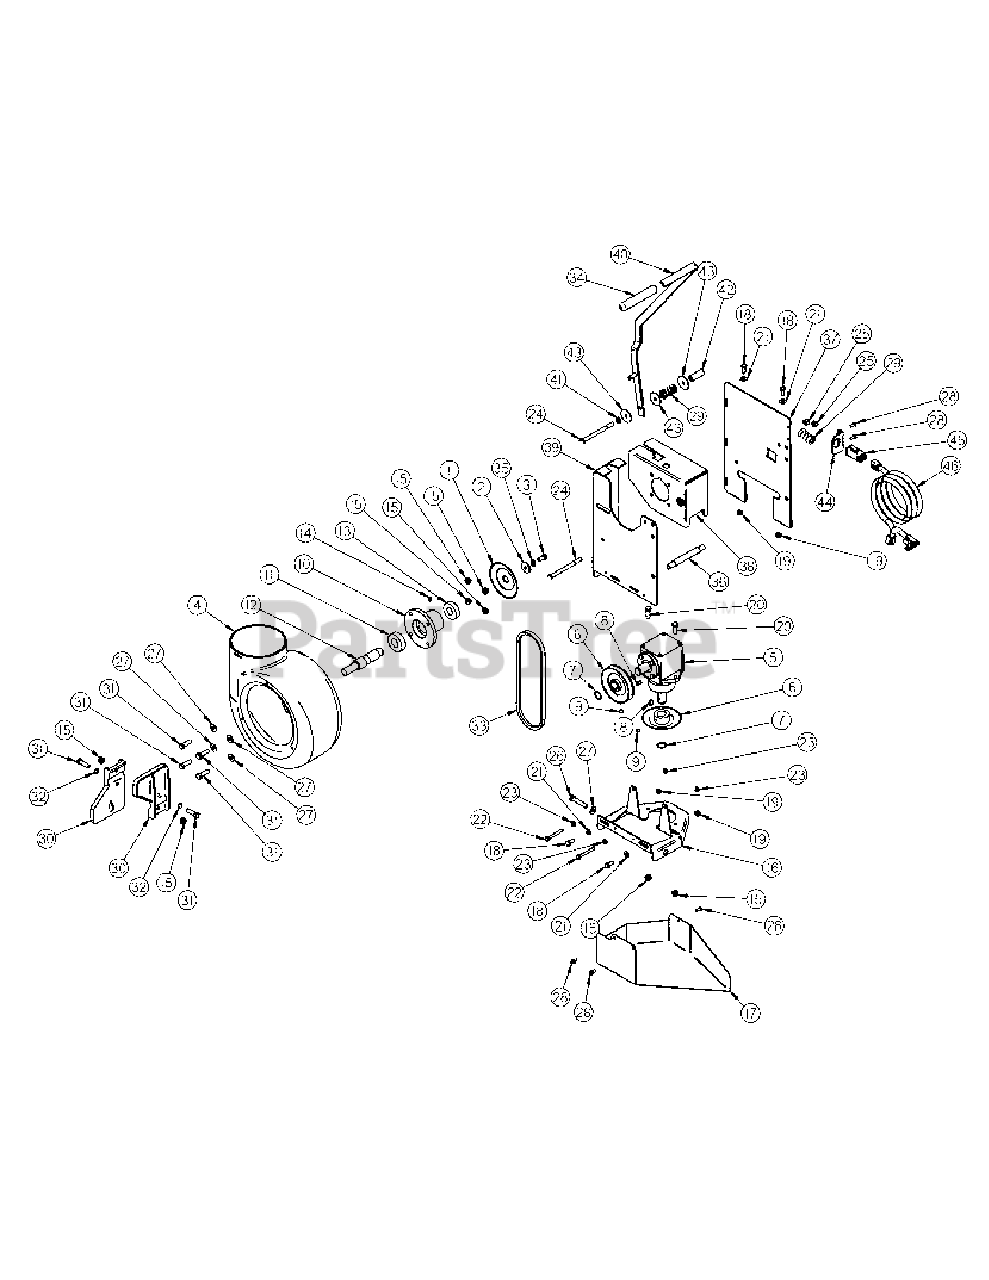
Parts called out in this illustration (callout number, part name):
1	'A' PULLEY FOR DECK DRIVE PTO
2	1.187 OD x .380 ID x .187 WASHER
3	3/8"-16 x 3/4" HHCS
4	BLOWER HSG.
5	GEAR BOX
6	PULLEY ASSY. FOR GEAR BOX
7	7/8" SNAP RING
8	#9 WOODRUFF KEY
9	5/16-18 SET SCREW
10	PTO SHAFT HOUSING
11	BEARING 2.0472 OD, 0.9843 ID, 0.5906 W (6205RS PEER)
12	PTO SHAFT
14	1/4"-28 ZIRC FITTING
15	3/8"-16 FLANGE NUT
17	GEAR BOX PULLEY GUARD
18	5/16"-18 x 3/4" HHCS
19	5/16"-18 FLANGE NUT
20	3/8"-16 x 1" HHCS
21	1/4" FLAT WASHER .75 OD x .314 ID x .060 T
22	1/4"-20 x 2-1/4" HHCS
23	1/4"-20 FLANGE NUT
24	3/8"-16 x 4-1/2" HHCS G5
25	3/8"-16 NYLOC NUT
26	3/8"-16 x 2" ALL THREAD HHCS
27	5/16" FLAT WASHER .875 OD x .380 ID x .075 T
28	1/4"-20 x 1/2" HHSTS
30	IMPELLER BLADE
31	3/8"-16 x 1-1/4" HHCS
32	3/8" INTERNAL LOCK WASHER
33	A28K KEVLAR BELT
34	5/8" ID x 4-3/4" BLACK HANDLE GRIP
35	3/8" LOCK WASHER
36	PTO ARM MNT. ROD
37	LT. PTO ARM
38	BLWR. MNT. BRKT.
39	RT PTO ARM
40	PTO HANDLE ASSY
41	SPACER BUSHING
42	SPACER BUSHING
43	WASHER 1-1/2" OD x 3/8" ID
44	SWITCH MOUNT BRACKET
45	PLUNGER SWITCH
46	SAFETY INTERLOCK HARNESS
